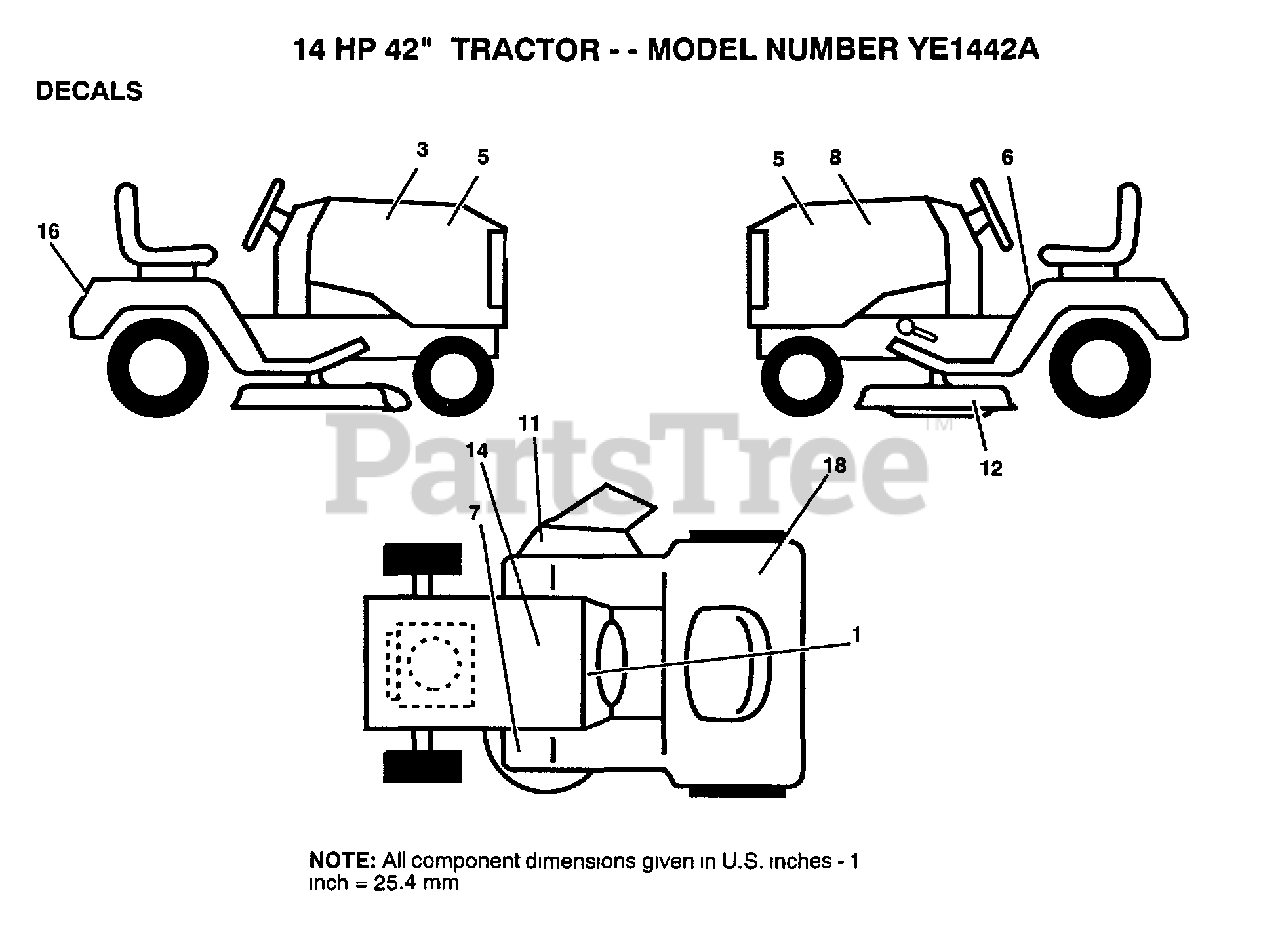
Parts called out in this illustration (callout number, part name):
6	DECAL CAUTION
7	DECAL T
8	DECAL HOOD LH
11	DECAL WARNING
12	DECAL YT
14	DECAL
